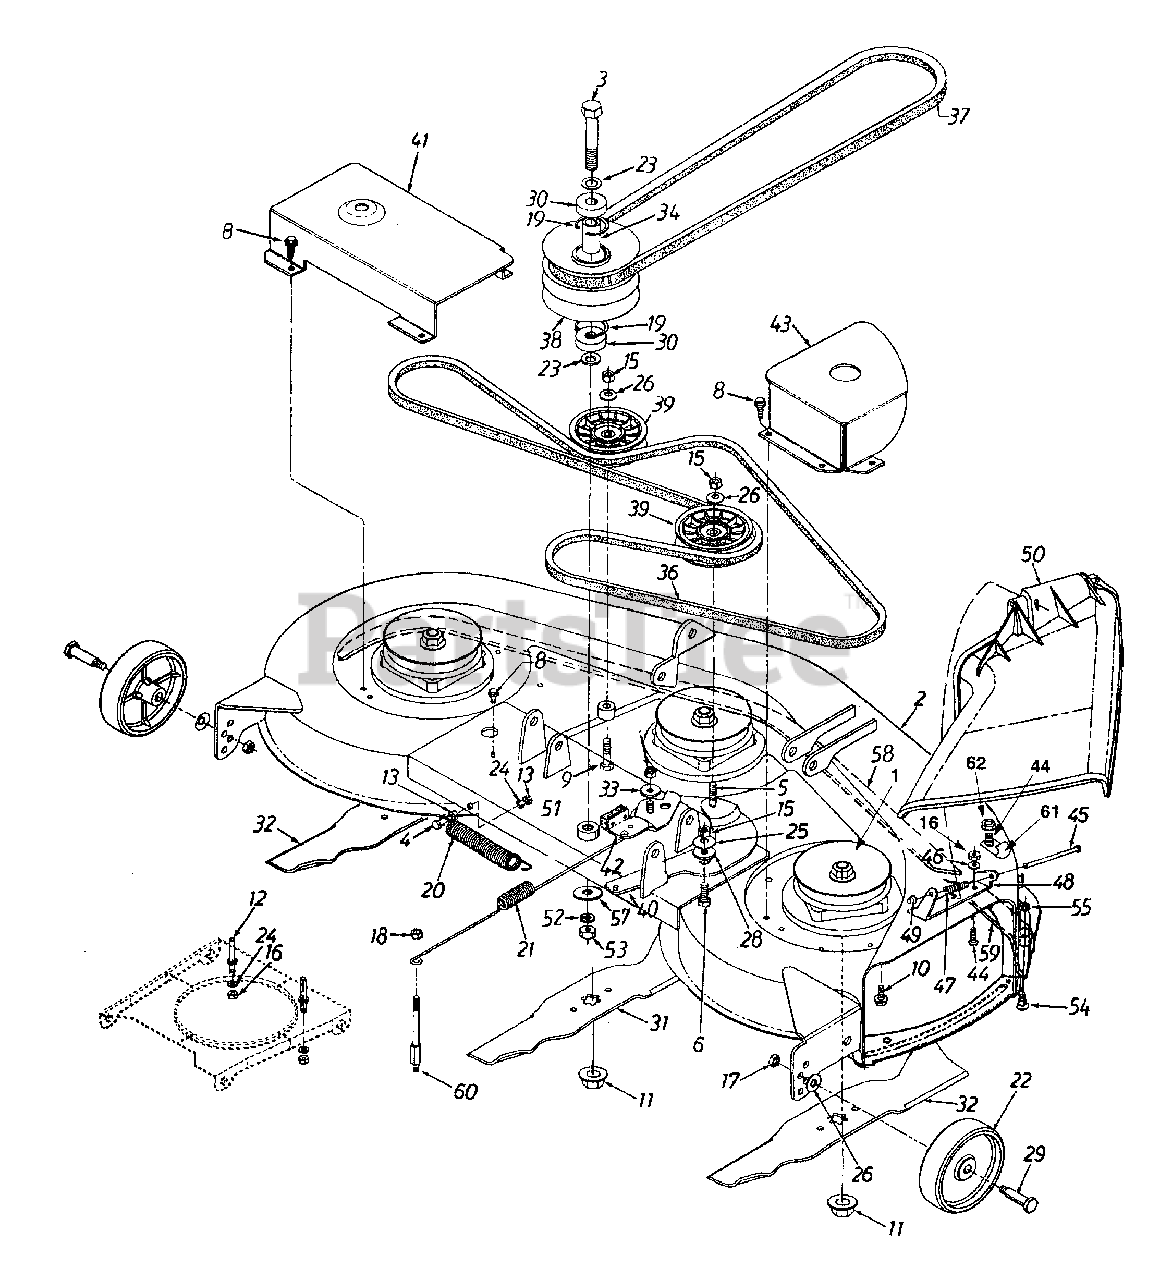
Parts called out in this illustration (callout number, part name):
1	Blade Spindle Assembly
4	Hex Bolt 1/4-28 x 1.25" Lg.
5	Hex Bolt 3/8-24 x 1.5" Lg.
6	Hex Bolt 3/8-24 x 1" Lg.
8	Hex Wash. Hd. TT-Tap Scr. 1/4-20 x .5"
9	Hex Bolt 3/8-24 x 2" Lg.
10	Hex Flange Bolt 5/16-24 x .75" Lg.
11	Hex Flange Lock Nut 5/8-18 Thd.
12	Belt Guard Pin
13	Hex Nut 1/4-28 Thd.
15	Hex Nut 3/8-24 Thd.
16	Hex Nut 1/4-20 Thd. (Gr. 5)
17	Hex Top Jam Nut 3/8-16 Thd.
18	Hex Center Lock Nut 5/16-18 Thd.
19	Int. Snap Ring
20	Ext. Spring .88" O.D. x 6.17"
21	Ext. Spring .788" O.D. x 15.5"
22	Deck Wheel
23	Flat Washer .635" I.D. x 1" O.D. x.06"
24	Lock Washer 1/4" I.D.
25	BelLock Washer 3/8" x 1.125" x .062"
26	BelLock Washer 3/8" x .87" x .064"
28	Shoulder Spacer .625" I.D. x .169"
29	Shld. Bolt .498" x 1.525"
30	Ball Brg 625" I.D. x 1.574" O.D. x .47"
31	Blade 14.88" Lg.
32	Blade 16.28" Lg.
33	Shoulder Spacer
34	Spacer .635" I.D. x .088" O.D.
36	V-Belt
37	V-Belt
38	Pulley Double Deck 5" O.D.
39	Flat Idler Pulley 3.5 O.D.
44	Hex Bolt 1/4-20 x .62" Lg.
45	Hinge Pin
46	BelLock Washer 1/4" I.D.
47	Torsion Spring
48	Hinge Mtg. Brkt.
49	Push Nut
50	Chute Assembly Complete
51	Spacer.635" I.D. x 1" O.D.
52	Lock Washer 5/8" I.D.
53	Hex Nut 5/8-18 Thd.
54	Carriage Bolt 1/4-20 x .5" Lg.
55	Hex Sems Nut 1/4-20 Thd.
57	Flat Washer .635" I.D.
60	Return Spring Stud
61	Retainer Hook Bracket
62	Hex Lock Nut 1/4-20
17258A-0648	Deck Belt Cover, 46" Black - TECH GRAY (0648)
17258A-0665	COVER:BELT:DECK 46 - YARDMAN GREEN (0665)
